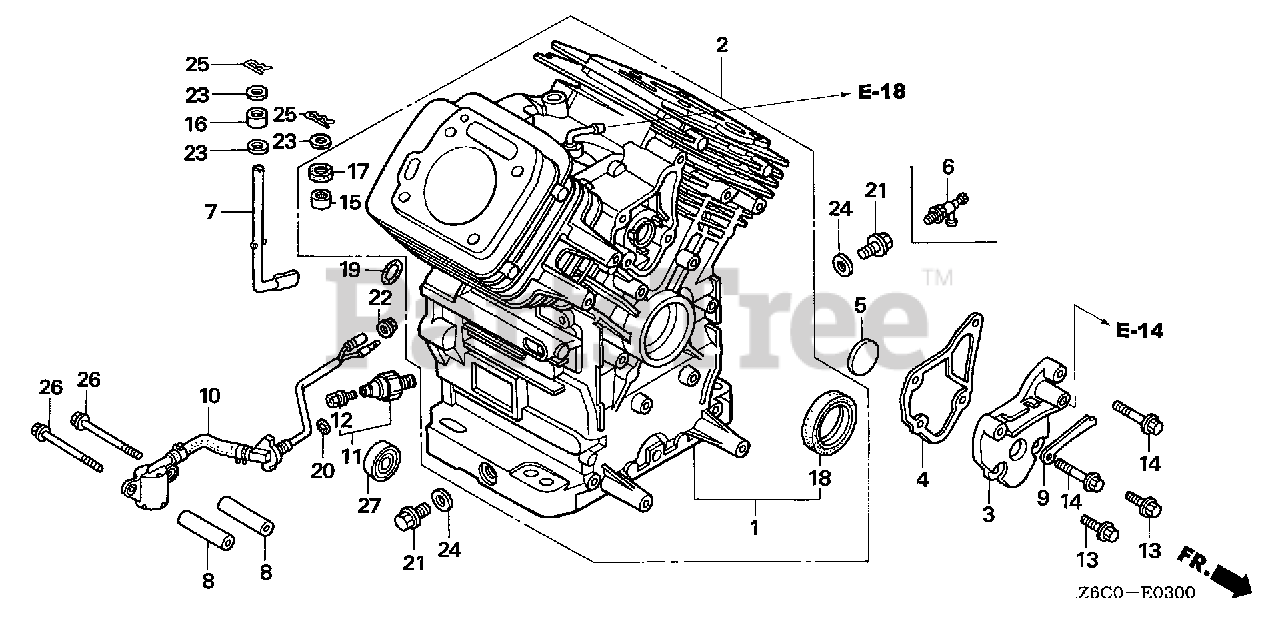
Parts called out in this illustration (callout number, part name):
2	CYLINDER ASSY. (NOT AVAILABLE)
2	CYLINDER ASSY.
3	COVER, BREATHER
4	GASKET, BREATHER COVER
5	VALVE, BREATHER
6	VALVE, DRAIN (14X1.5)
7	SHAFT, GOVERNOR ARM
9	CLAMP, WIRE
11	SWITCH ASSY., OIL PRESSURE
11	SWITCH, OIL PRESSURE
12	SCREW-WASHER (4X8)
13	BOLT, FLANGE (6X16) (CT200)
14	BOLT, FLANGE (6X32) (CT200)
15	BEARING, NEEDLE (8X12.7X11.1)
16	BEARING, NEEDLE (8X12X10)
17	OIL SEAL (8X14X5)
18	OIL SEAL (38X58X9)
19	O-RING (13X3.0)
21	BOLT, DRAIN PLUG (14MM)
23	WASHER, PLAIN (8MM)
24	WASHER, DRAIN PLUG (14MM)
25	PIN, LOCK (8MM)
27	BEARING, RADIAL BALL (6003)
